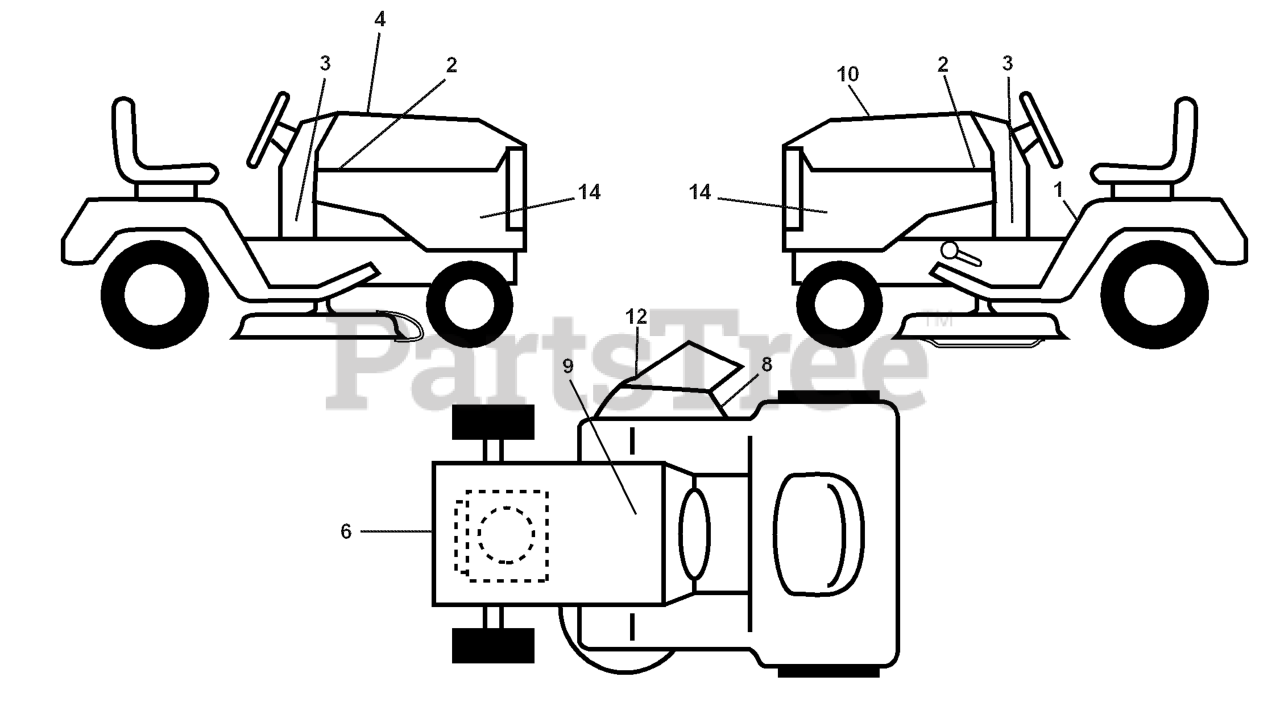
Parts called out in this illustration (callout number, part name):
1	DECAL.FENDER.WARNING.ENG
2	EMBLEM.HOOD.HUSQ.DEALER
4	DECAL.RPL.BSM44.ENDR.TGW.54K6
6	DECAL.ENG.BSM44.ENDUR.27HP
8	DECAL.MOWER.SCH.48/54
9	DECAL BTRY SYMBOLS
10	DECAL HOOD CUST. RESP.
12	DECAL.WARN.KEEP.HAND.AWAY
14	DECAL.SDPNL.2754GLS.ENDUR.HUSQ
